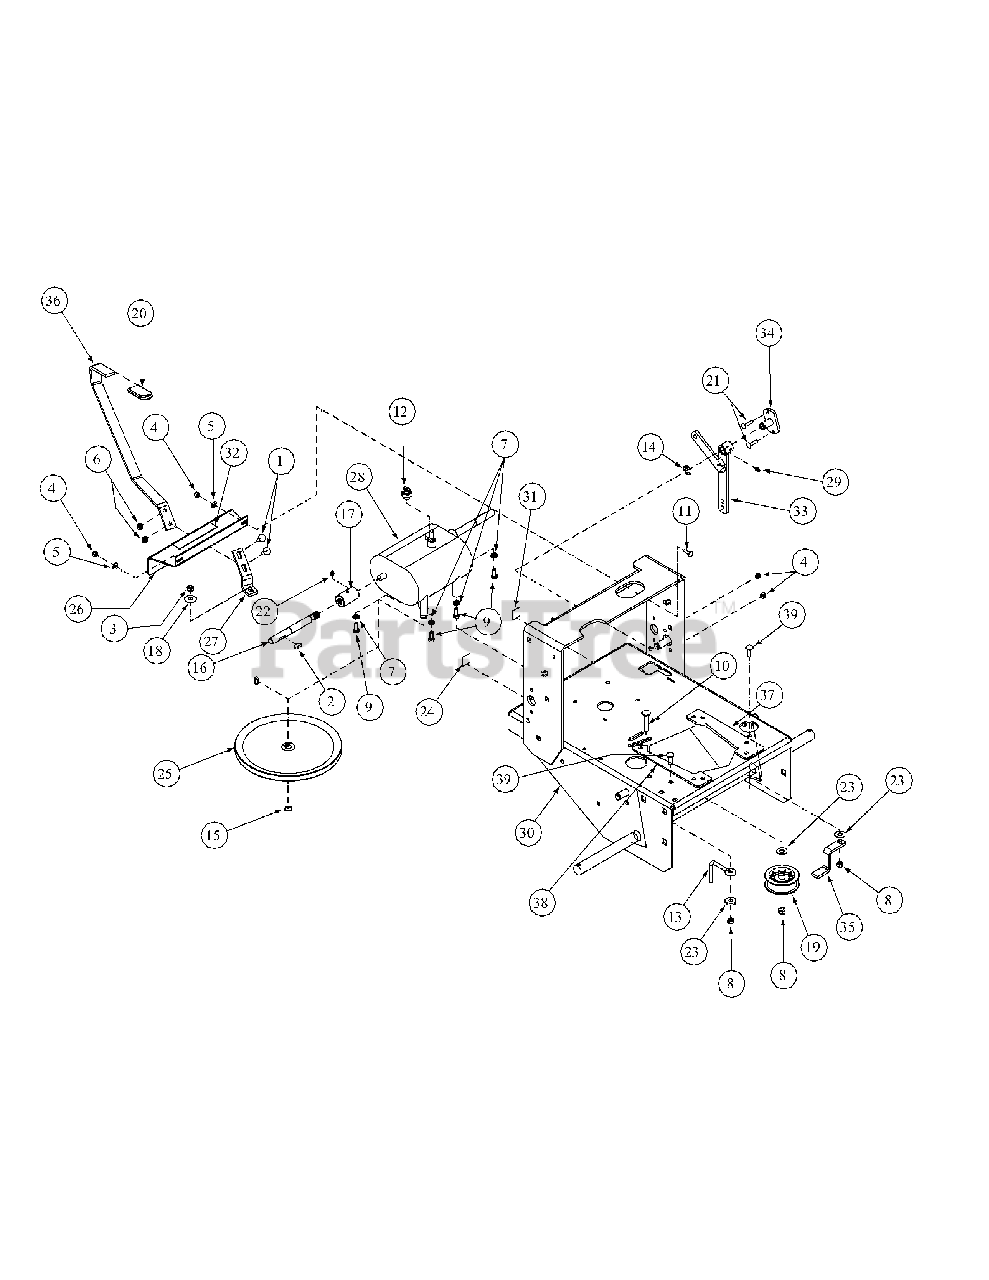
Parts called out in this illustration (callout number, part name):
1	Carriage Bolt, 5/16-18 x 1
2	Woodruff Key, 3/16 x 3/4
3	Jam Nut, Insert Lock, 3/8-24
4	Lock Nut, Nylon Insert, 1/4-20
5	Flat Washer, 1/4 Zinc
6	Nut, 5/16-18 Nylock
7	Lock Washer, 5/16 Zinc
8	Lock Nut, Nylon Insert, 3/8-16
9	Hex Cap Screw, 5/16-18 x 3/4
10	Carriage Bolt, 3/8-16 x2
11	Carriage Bolt, 1/4-20 x .750
12	Switch, WB Transmission
13	Drive Belt Guide
14	E-Ring, 5/8
15	External Retainer Ring
16	Jackshaft w/ Heavy Spline
17	Coupling w/Heavy Spline
18	Bell Washer, .39 ID x 1.13 OD x .062
19	Flat Idler Pulley w/Adapter
20	Grip, .250 x 1 x 3-1/2, Yellow
21	Carriage Bolt, 1/4-20 x 1.00
22	Grease Fitting, 1/4-28 x 3/16
23	Idler Washer
24	Decal "Made In America
25	Transmission Pulley
27	Shift Arm
28	Transmission, 5 Speed
29	Grease Fitting, 1/4-28 x 1/2
30	Engine Deck Assembly
31	Label, Warning, Open Belt Drive
32	Label, Mower Instruction
33	Clutch, Bellecrank Weldment
34	Bellecrank Pivot, Weldment
35	Engine Belt Guide
37	Engine Spacer, LH
38	Engine Spacer, RH
39	Carriage Screw, 3/8-16 x 1.25
